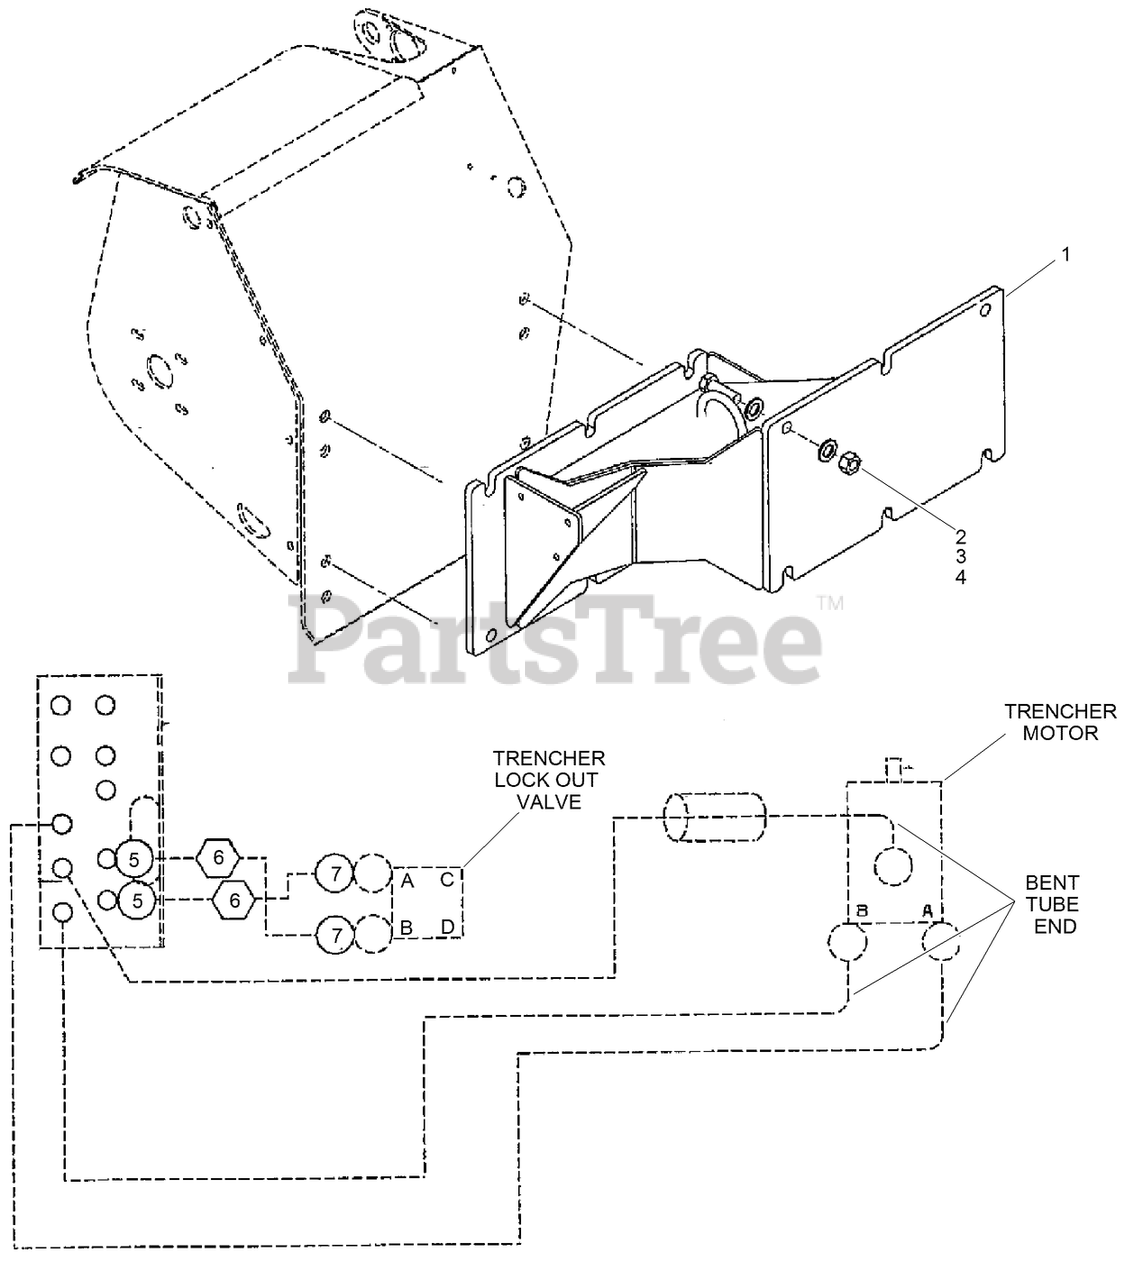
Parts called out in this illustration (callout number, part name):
1	WELDMENT - Offset Trencher
5	FITTING-ELBOW, 45 DEG
6	HOSE - Bulkhead to Lockout Valve
7	ELBOW-SWIVEL, 90 DEG
